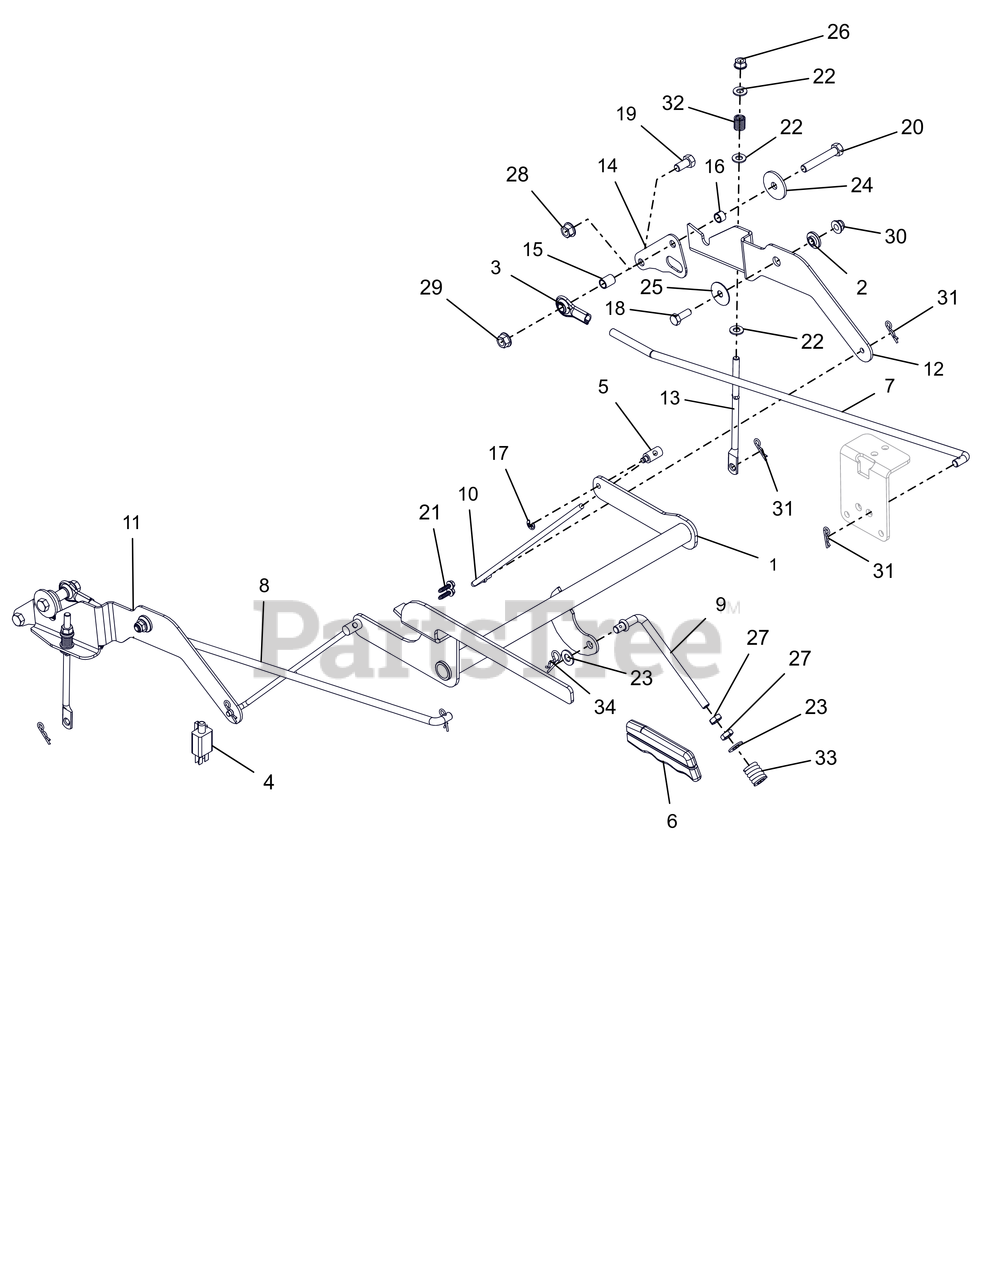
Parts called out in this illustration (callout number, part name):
1	WLDMT, BRAKE LEVER
2	BSHG, FLG .325X.499X.26X.88
3	ROD END, .38 RH
4	SWITCH- DOUBLE POLE N.O./N.O.
5	TRUNION, 1/4-20
6	GRIP, PARKING BRAKE (YELLOW)
7	STEERING, LINKAGE LH
8	STEERING, LINKAGE RH
9	LINK, OVER CENTER, PARKING BRK
10	LINK, BRAKE ARM
11	INTERLOCK, RH BRAKE LINK
12	INTERLOCK, LH BRAKE LINK
13	LINK, BRAKE COG
14	PLATE, TRANSAXLE ADAPTOR
15	SPCR, SLV .385X.500X.652
16	SPCR, SLV .385X.500X.350
17	RG-RTNG-EXT .250X.025
18	BLT, HEX .31-18X.875 G5 ZCC
19	BLT,HEX .38-16X.75 G5 ZCC
20	BLT,HEX .38-16X2.25 G5 ZCC
21	SCR, PLASTITE #12X.75 ZCC
22	WSHR,FLT .344X.688X.065 ZCC
23	WSHR,FLT .406X.812X.065 ZCC
24	WSHR, FLT .380X1.50X.125 ZCC
25	WSHR, FLT .347X1.254X.048 ZCC
26	NUT,LK-CTR-FLG .31-18 GF ZCC
27	NUT-JAM .375-16 G2 ZCC
28	NUT-LK-TOP-FLG .38-16 ZC120
29	NUT-LK-CTR-FLG .375-16 GF ZCC
30	NUT,LK-NYL-FLG .31-18 G5ZC120
31	PIN, HAIR #213 .08X1.19 ZCC
32	SPRING, COMPRESSION
33	SG-COMP .187X.56X1.62
34	PIN-HAIR CTR .09 X 1.50 YWZC
